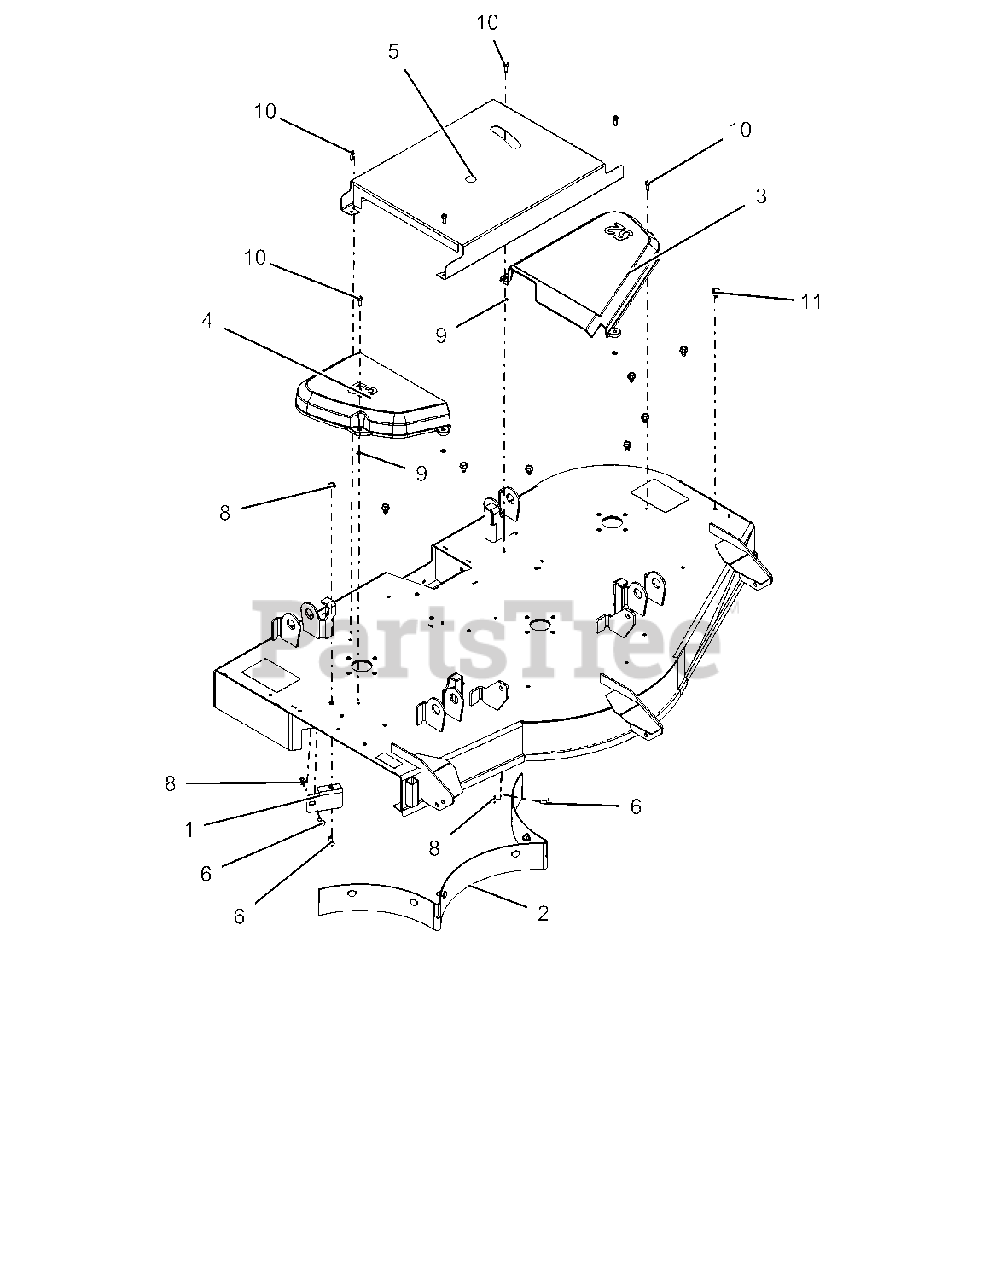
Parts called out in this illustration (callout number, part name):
1	STRIP, DEFLECTOR - 52"
2	BAFFLE, REAR - REMOVABLE 52"
3	COVER, BELT 52" LH
4	COVER, BELT 52" RIGHT
5	GUARD, IKON BELT - 52" CE
6	@BLT-RDHDSQNK .31-18X.75 G5YZ
8	@NUT-LK-TOP-FLG .31-18 YWZC
9	NUT-PUSH .25X.50 O.D.
10	SCR-TAP-PM .25-20X.75 TR YWZ
11	@SCR-TAP .38-16X.50 HWH TR YWZ
